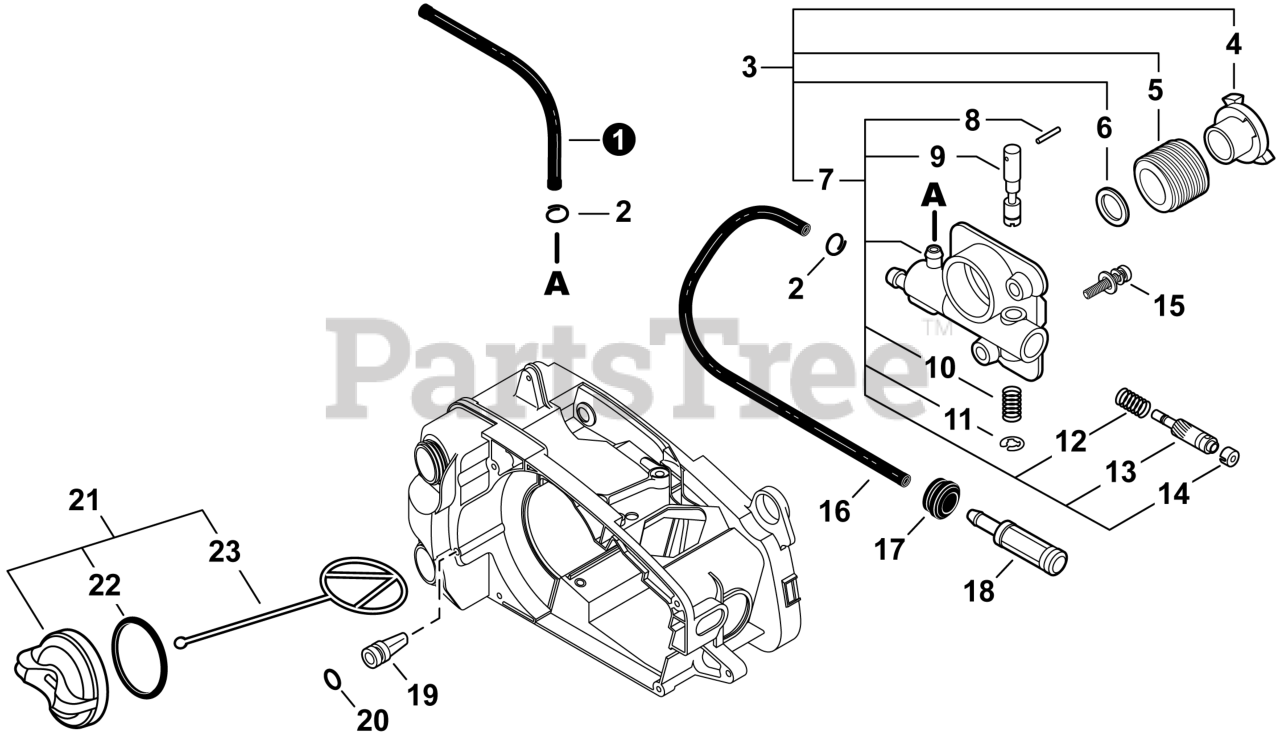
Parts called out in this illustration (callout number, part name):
1	PIPE 3×6×90 MM
2	CLIP Ø6.5 MM
3	AUTO-OILER ASSY
4	COLLAR 10
5	GEAR, WORM
6	WASHER 10.5×17.4×1.8
7	AUTO-OILER
8	PIN, SPRING
9	ADJUSTER, OILER
13	PLUNGER ASSY
14	CAP, OIL PUMP
15	SCREW 4×12
16	PIPE 3×6×160
18	FILTER, OIL
19	CHECK VALVE
21	CAP ASSY - BLACK
22	O-RING 18
23	FUEL CAP CONNECTOR (L=60MM)
